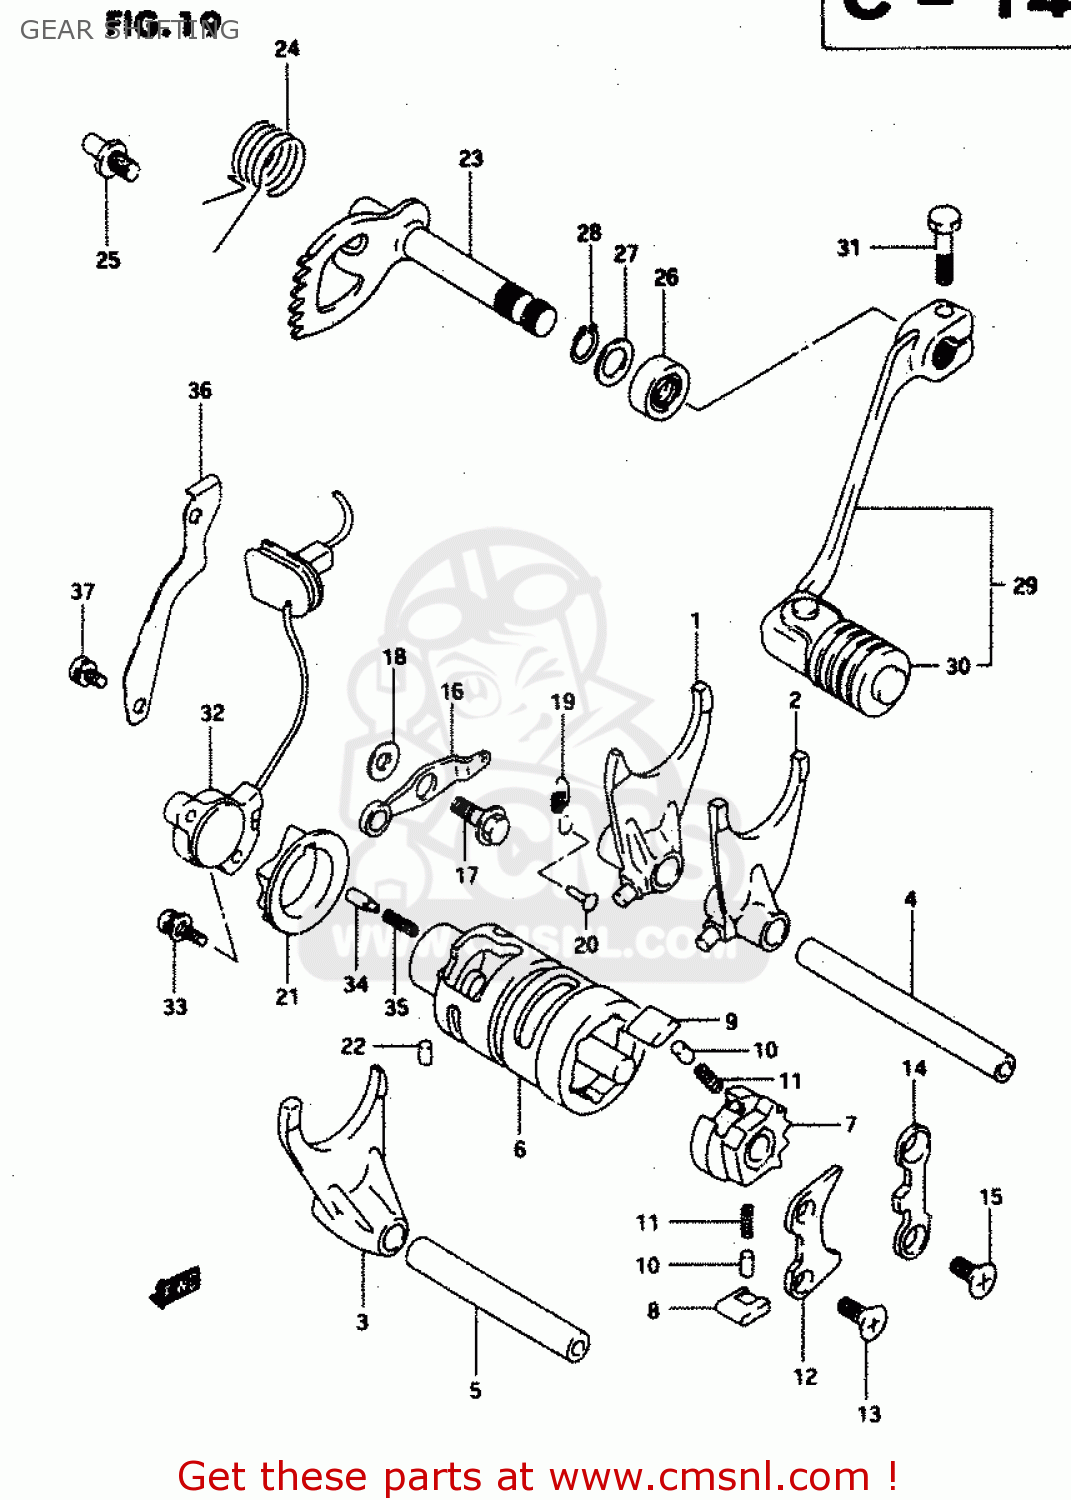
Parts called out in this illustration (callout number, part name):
1	FORK,GEAR SHIFT NO.1
2	FORK,GEAR SHIFT NO.2
3	FORK,GEAR SHIFT NO.3
4	SHAFT,GEAR SHIFT FORK
5	SHAFT,GEAR SHIFT FORK
6	CAM,GEAR SHIFT
7	GEAR,GEARSHIFT CAM DRIVE
8	PAWL,GEAR SHIFT NO.1
9	PAWL,GEAR SHIFT NO.2
10	PIN(5X8)
11	SPRING
12	LIFTER,GEAR SHAFT PAWL
13	SCREW
14	STOPPER,GEAR SHIFT POLE
15	SCREW
16	STOPPER,GEAR SHIFT CAM
17	BOLT(6X14.6)
18	WASHER
19	SPRING
20	RIVET
21	PLATE,GEAR SHIFT CAM STOPPER
22	PIN 4X6
23	SHAFT,GEAR SHIFT
24	SPRING
25	STOPPER,GEAR SHIFT CAM
26	OIL SEAL
27	WASHER
28	CIRCLIP,12 MM
29	LEVER ASSY,GEAR SHIFT
30	RUBBER,GEAR SHIFT PEDAL
31	BOLT
32	BASE ASSY,NEUTRAL SW TERMINAL
33	SCREW
34	PIN(5X15.5)
35	SPRING
36	CLAMP,LEAD WIRE
37	SCREW
